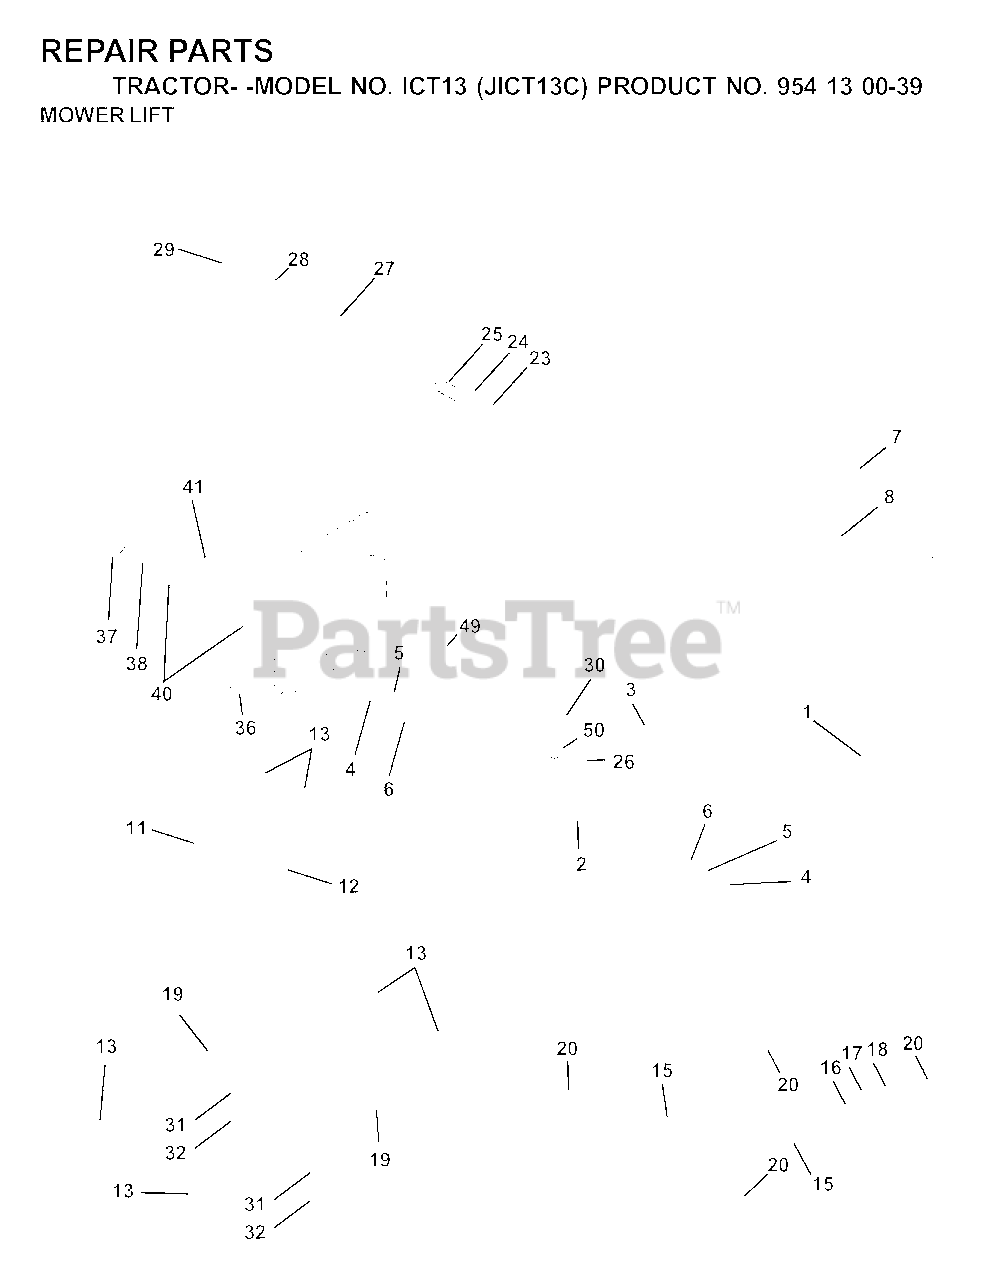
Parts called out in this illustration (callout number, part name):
1	WIRE ASM INNER W/ PLUNGER LT
2	SHAFT ASM R HANDLE
3	PIN GROOVE
4	RETAINING RING LT
6	BEARING.NYLON
7	GRIP HANDLE
8	PLUNGER BUT KIT
11	LINK
12	LINK
13	RETAINER-SPRNG RB
15	LINK.SUSPENSION.FRONT
16	NUT
17	TRUNION
18	NUT
19	ARM.REAR.SUSPENSION
20	SPRING RETAINER
25	SPRING**
26	RETAINER CLIP
27	ROD ADJ LIFT
28	NUT
29	KNOB INF 3/8-16
31	BEARING PIVOT
32	NUT CROWNLOCK 3/8-24
36	POINTER, HEIGHT INDICATOR
37	PLUG,HOLE
38	SCREW 5/16-18X1
41	HEIGHT INDICATOR
49	NUT
50	NUT PUSH M
